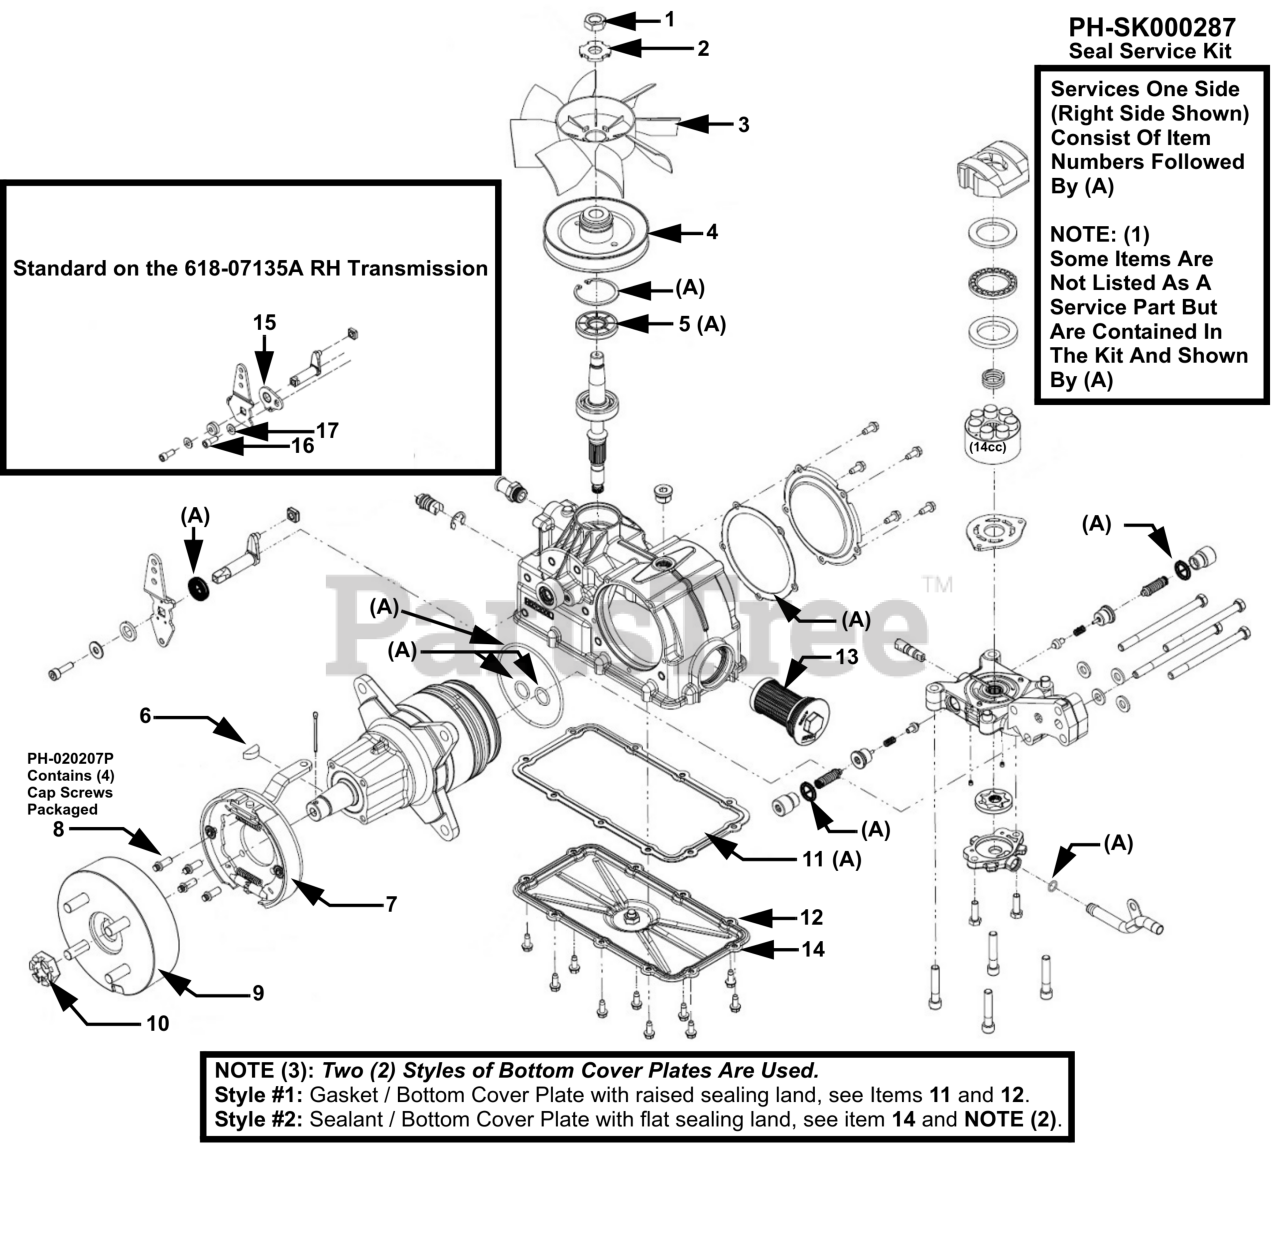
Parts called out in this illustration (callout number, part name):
6	WOODRUFF KEY
7	BRAKE ASSEMBLY-ON HOLE LEVER
8	SCREW-CAP (QTY 4)
9	DRUM-4 BOLT BRAKE
10	NUT-SLOTTED
11	BOTTOM COVER GASKET
12	BOTTOM COVER
14	BOTTOM COVER
15	TRUNNION ARM BRACKET (RH)
16	CAP SCREW 5/16-24
17	FLAT WASHER
A	SEAL SERVICE KIT
